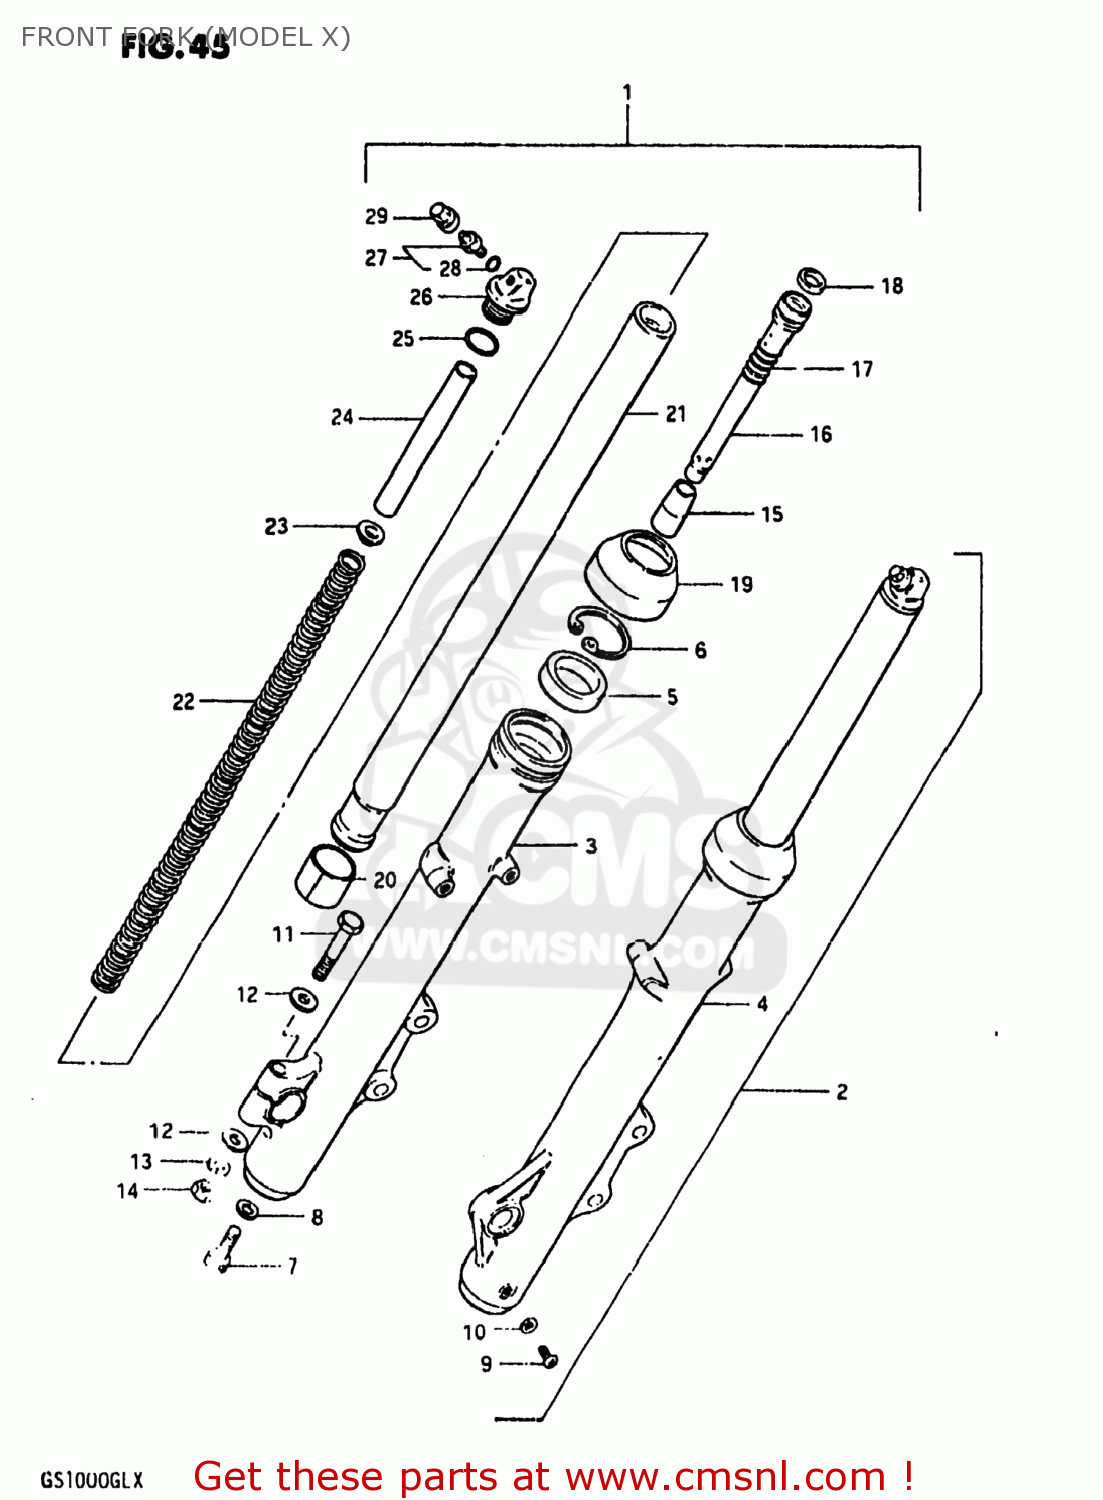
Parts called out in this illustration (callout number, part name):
1	DAMPER ASSEMBLY,RIGHT
2	DAMPER SET
3	TUBE,FORK,OUTER,RIGHT
4	TUBE,OUTER,LEFT
5	OIL SEAL,FRONT FORK
6	RING,STOPPER
7	BOLT,FORK CYLINDER(10X25)
8	GASKET (NAS)
9	SCREW
10	GASKET,DRAIN,PLUG (NAS)
11	BOLT 8X50
12	WASHER
13	WASHER,LOCK,8.
14	NUT
15	PIECE,OIL LOCK
16	CYLINDER,FRONT FORK
17	SPRING,REBOUND
18	RING,PISTON
19	SEAL,DUST
20	PISTON
21	TUBE,INNER
22	SPRING,FRONT FORK
23	GUIDE,FRONT FORK SPRING C
24	COLLAR,SPRING
25	O RING
26	CAP
27	VALVE
28	O RING
29	CAP,VALVE
